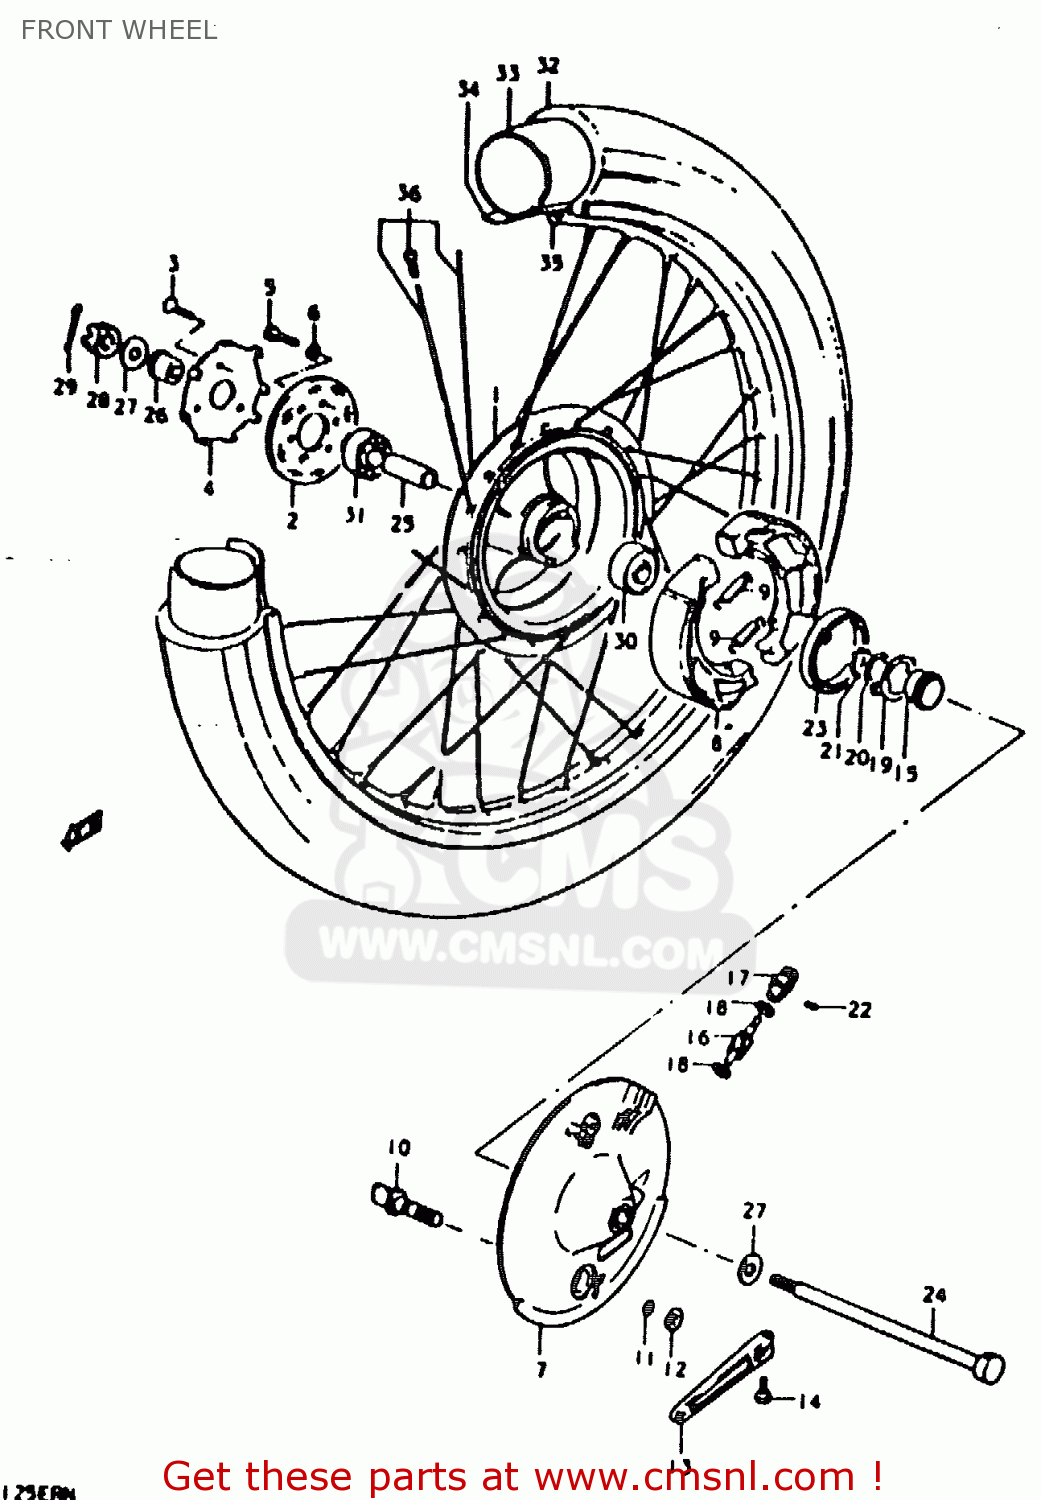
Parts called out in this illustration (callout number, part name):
1	HUB,FR WHEEL
2	FLANGE,FR HUB,R
3	SCREW
4	RETAINER, HUB BEARING RH
5	BOLT, UPPER
6	LOCK WASHER
7	PANEL,FRONT HUB
8	SHOE,BRAKE
9	SPRING(L:34)
10	CAM,FRONT BRAKE
11	O-RING (D:2.4 ID:13.8)
12	WASHER (14.5X22X1.6)
13	LEVER,FRONT BRAKE CAM
14	BOLT
15	GEAR,SPEEDOMETER
16	PINION,SPEEDOMETER
17	BUSH,METER GEAR OUTER
18	WASHER (5.1X9X0.4)
19	DRIVER,SPEEDOMETER GEAR
20	WASHER(18.5X24X1)
21	CIRCLIP
22	SCREW
23	OIL SEAL (43X58X7)
24	AXLE,FRONT
25	SPACER (12.6X19X52)
26	SPACER,FR AXLE,R
27	WASHER
28	NUT 12MM
29	COTTER PIN
30	BEARING
31	BEARING, RH
32	TIRE,FR
33	TUBE
34	PROTECTOR,WHEEL,INNER
35	RIM,FR WHEEL(1.60X21)
36	SPOKE SET,FRONT
